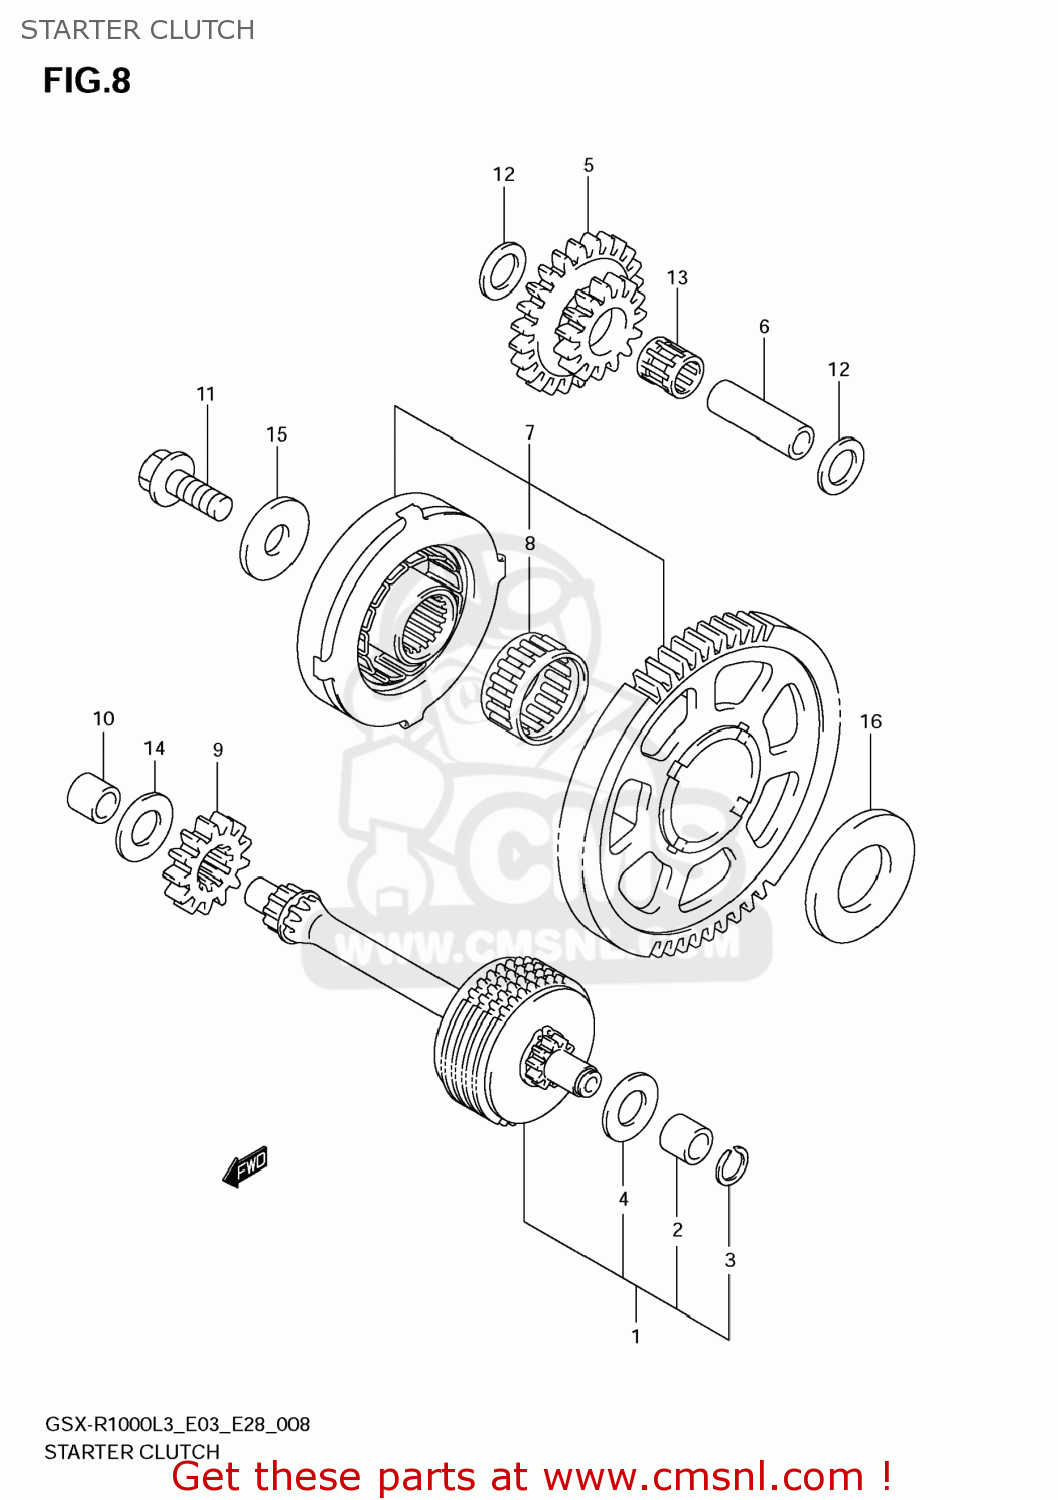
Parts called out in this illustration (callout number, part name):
1	LIMITER ASSY,START ID GR NO.1
2	BUSH,LIMITER GEAR SHAFT
3	CIRCLIP
4	WASHER
5	GEAR,STARTER IDLE NO.2
6	PIN,PISTON
7	CLUTCH SET,STARTER
8	BEARING(26X31X16)
9	GEAR,LIMITER DRIVEN
10	BUSH,LIMITER GEAR SHAFT
11	BOLT(10X23)
12	SHIM(12X20X1)
13	BEARING(12X16X16)
14	WASHER
15	WASHER
16	WASHER
